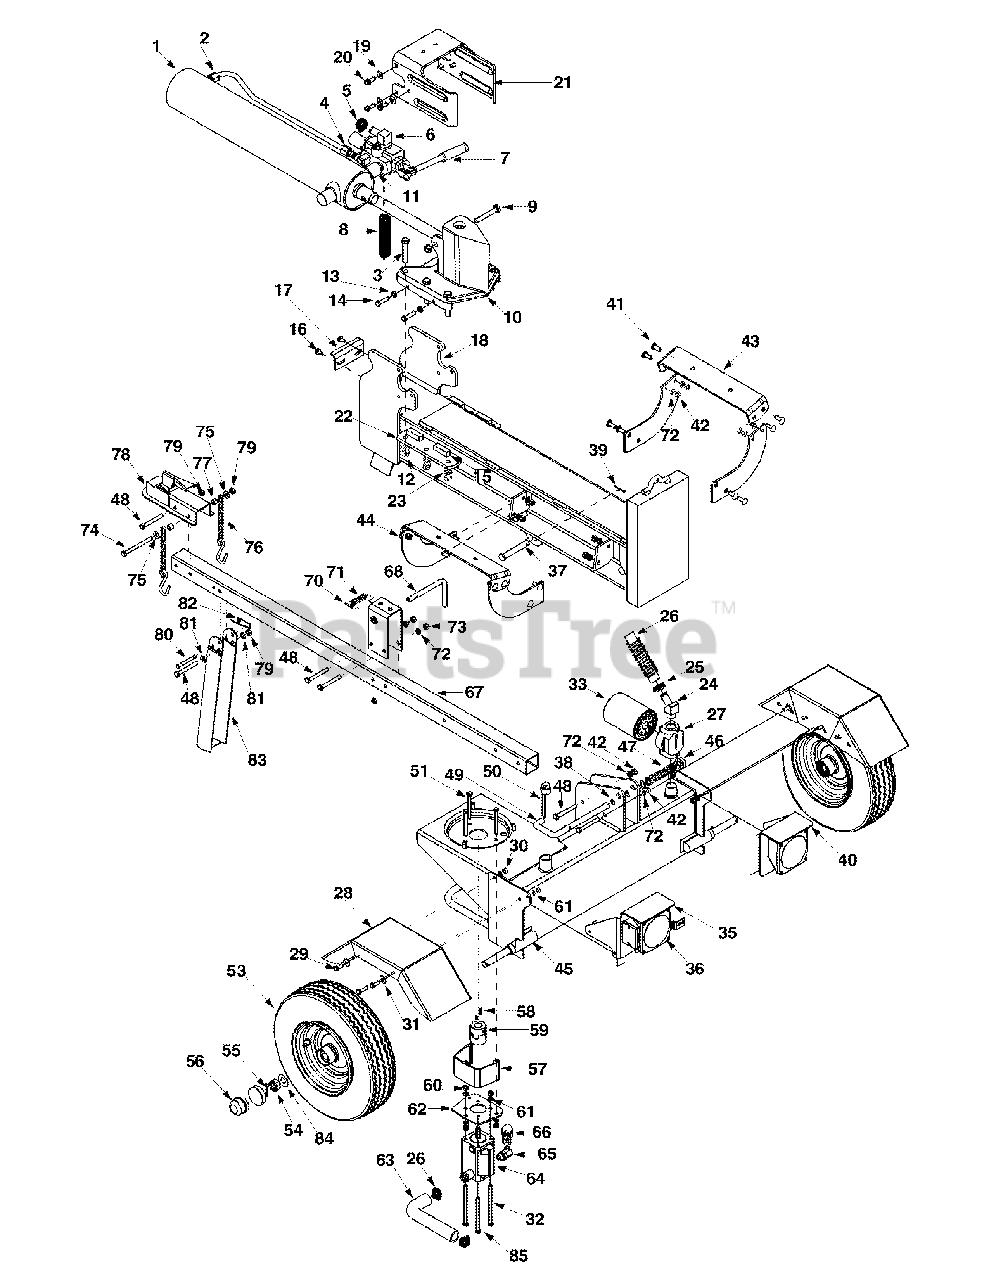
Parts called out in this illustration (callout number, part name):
1	Hydraulic Cylinder
2	Hydraulic Tube
3	Hex Cap Screw 1/2-20 x 2.75
4	90 Degree Solid Adapter
5	Hose Guard
6	Return Elbow
8	Hose Guard
9	Hex Cap Screw 1/2-20 x 3.50
10	Wedge Assembly
11	Nipple Pipe 1/2-14
12	Lock Nut 1/2-20
13	Hex Jam Nut 3/8-24
14	Hex Cap Screw 3/8-24 x 1.5
15	Adjustable Gib
16	Hex Washer Screw 5/16-18 x .625
19	Flat Washer .406 ID x .875 OD
20	Hex Washer Screw 3/8-16 x 1.0
23	Lock Washer 1/2
24	Adapter 3/4-14
25	Return Hose 3/4" ID x 44" Lg.
26	Hose Clamp 5/8"
27	Filter Housing
29	Hex Screw
30	Hex Nut 5/16-18
31	Lock Washer 5/16
32	Hex Bolt 5/16-24 x 5.25"
33	Oil Filter
34	Hex Cap Screw 5/16-18 x 1.0
36	Taillight Kit
37	Clevis Pin
38	Flat Washer .635 ID x .93 OD
39	Cotter Pin
41	Carriage Bolt 3/8-16 x 1.0
42	Hex Nut 3/8-16
47	Compression Spring
48	Hex Bolt 3/8-16 x 3"
50	Vented Dipstick
51	Hex Screw 5/16-24 x 3.25
52	Hex Washer Screw 3/8-16 x 1.0
53	Wheel Assembly
54	Slotted Nut 3/4-16
55	Cotter Pin
57	Coupling Shield
58	Square Key 3/16" x .75
59	Flexible Coupling .875 x .437 ID "Stamped L075"
59	Flexible Coupling .750 x .500
59	Flexible Coupling .875 x .500
60	Hex Nut 5/16-24
61	Lock Washer 5/16" ID
64	Gear Pump (11gpm)
64	Pump Kit
64	Gear Pump (9.5 gpm)
65	45 Degree Elbow
66	High Pressure Hydraulic Hose
68	Latch Rod
70	Spiral Pin
71	Spring Compression
72	L-Washer 3/8"
73	Hex Nut 3/8-16
74	Hex Cap Screw 3/8-16 x 4.25
75	Flat Washer .385 ID x .870 OD
76	Chain
77	Spacer .375 ID x .625 OD
78	Coupling Hitch
79	Hex Lock Nut 3/8-16
80	Clevis Pin
81	Flat Washer .375 ID x .738 OD
82	Spring Pin
85	Hex Bolt 5/16-18 x 4.5"
